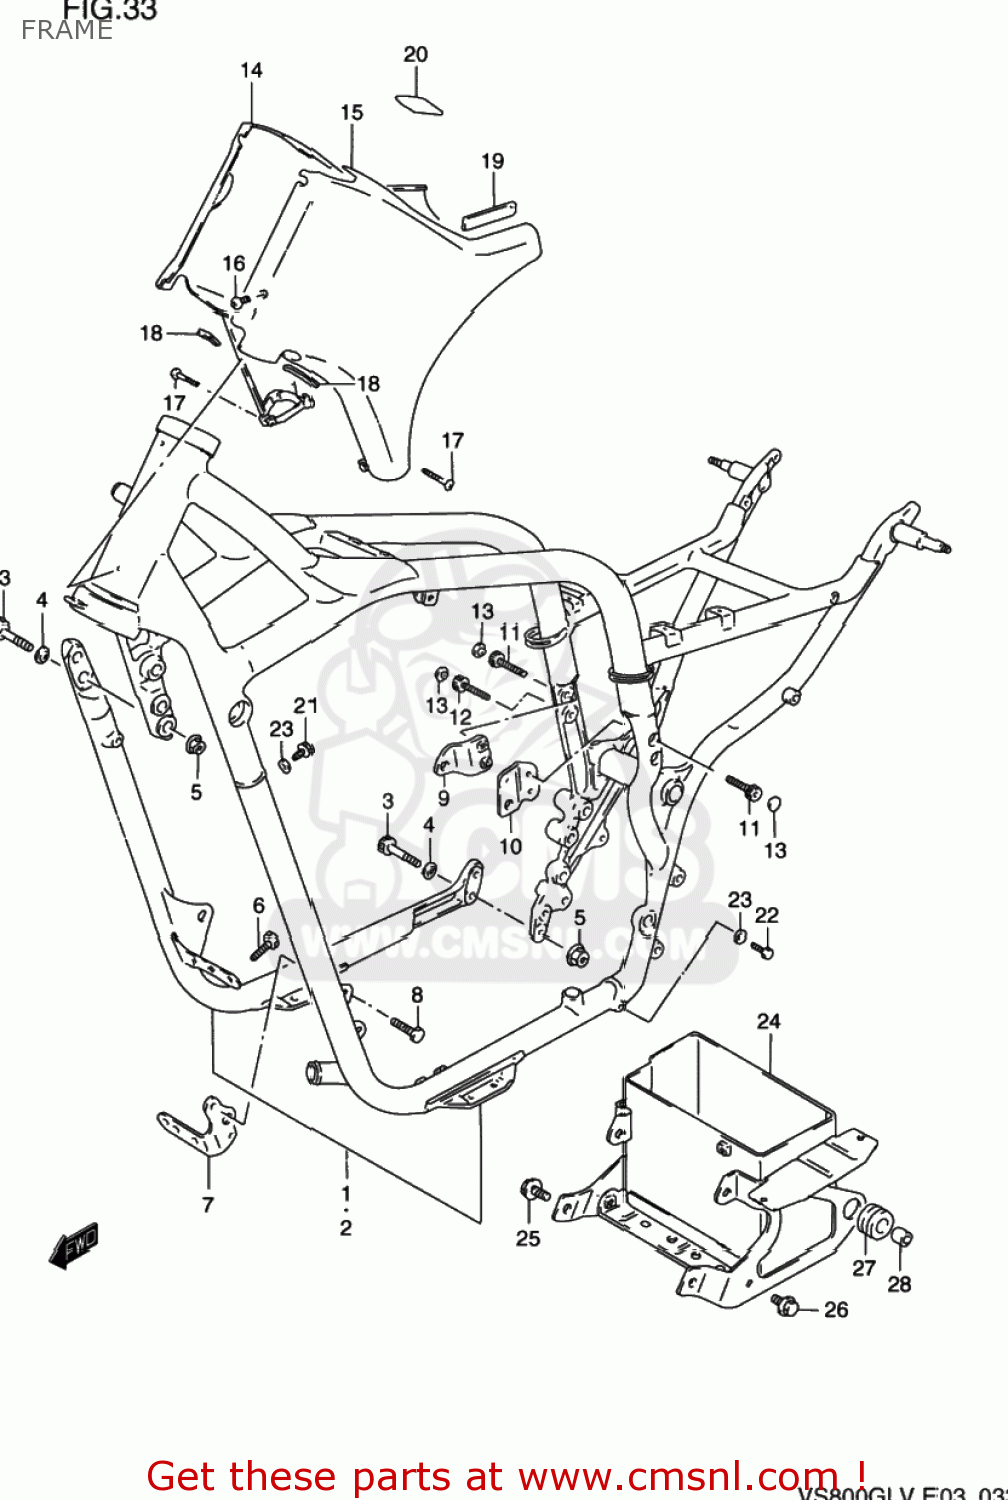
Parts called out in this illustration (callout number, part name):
1	FRAME
2	FRAME SET
3	BOLT(10X33)
4	WASHER
5	NUT 10MM
6	BOLT
7	PLATE,ENGINE MOUNTING
8	BOLT
9	PLATE,ENGINE MOUNTING NO
10	PLATE,ENGINE MOUNTING NO
11	BOLT(8X30)
12	BOLT
13	CAP(OD:14.5)
14	COVER,FRAME HEAD,RIGHT
15	COVER,FRAME HEAD,LEFT
16	SCREW 5X10
17	SCREW
18	MOLDING,FUEL TANK
19	PROTECTOR(20X90)X2
20	TAPE,FRAME HEAD COVER
21	UNION
22	BOLT
23	GASKET(6.2X11X1).2 (NAS)
24	HOLDER,BATTERY
25	BOLT
26	BOLT
27	CUSHION
28	BUSH
